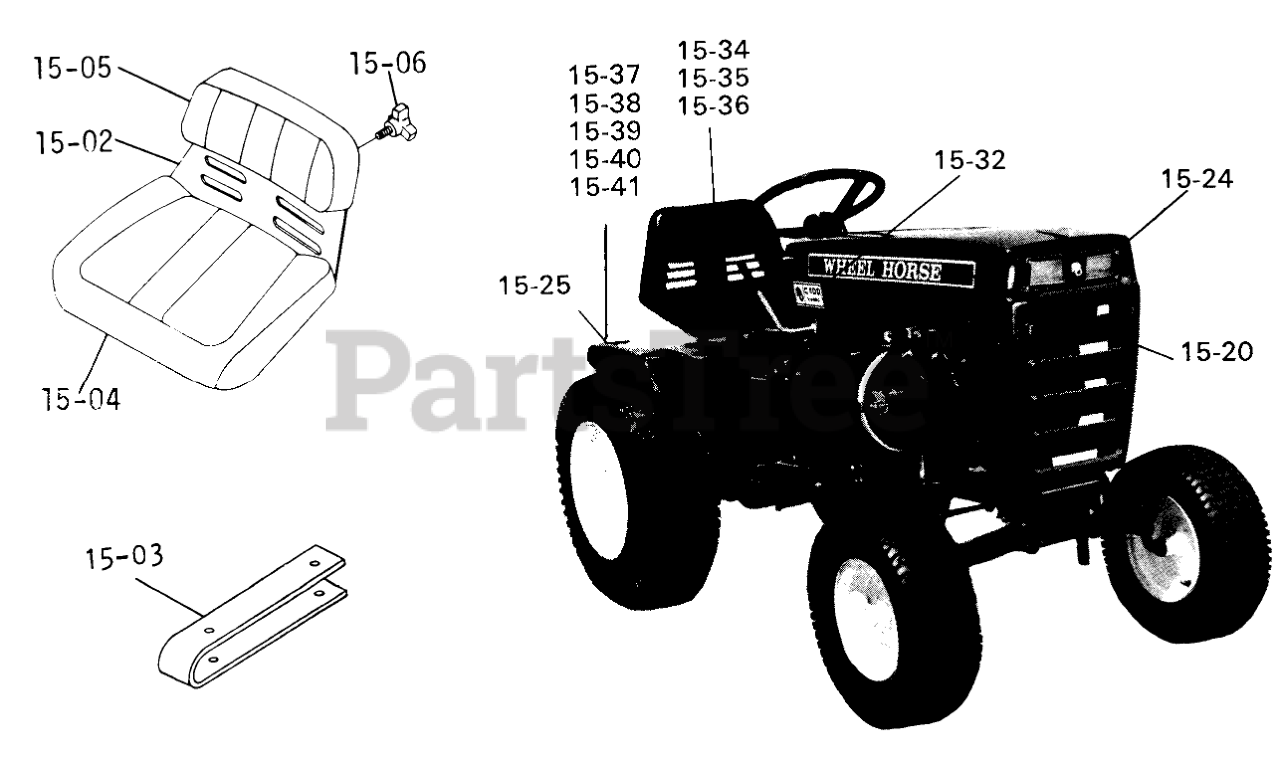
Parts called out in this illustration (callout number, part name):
15-04	BULLT 281
15-05	BULLT 281
15-34	Washer
15-35	Decal-Read Manual
15-36	DECAL-HAND LIFT
